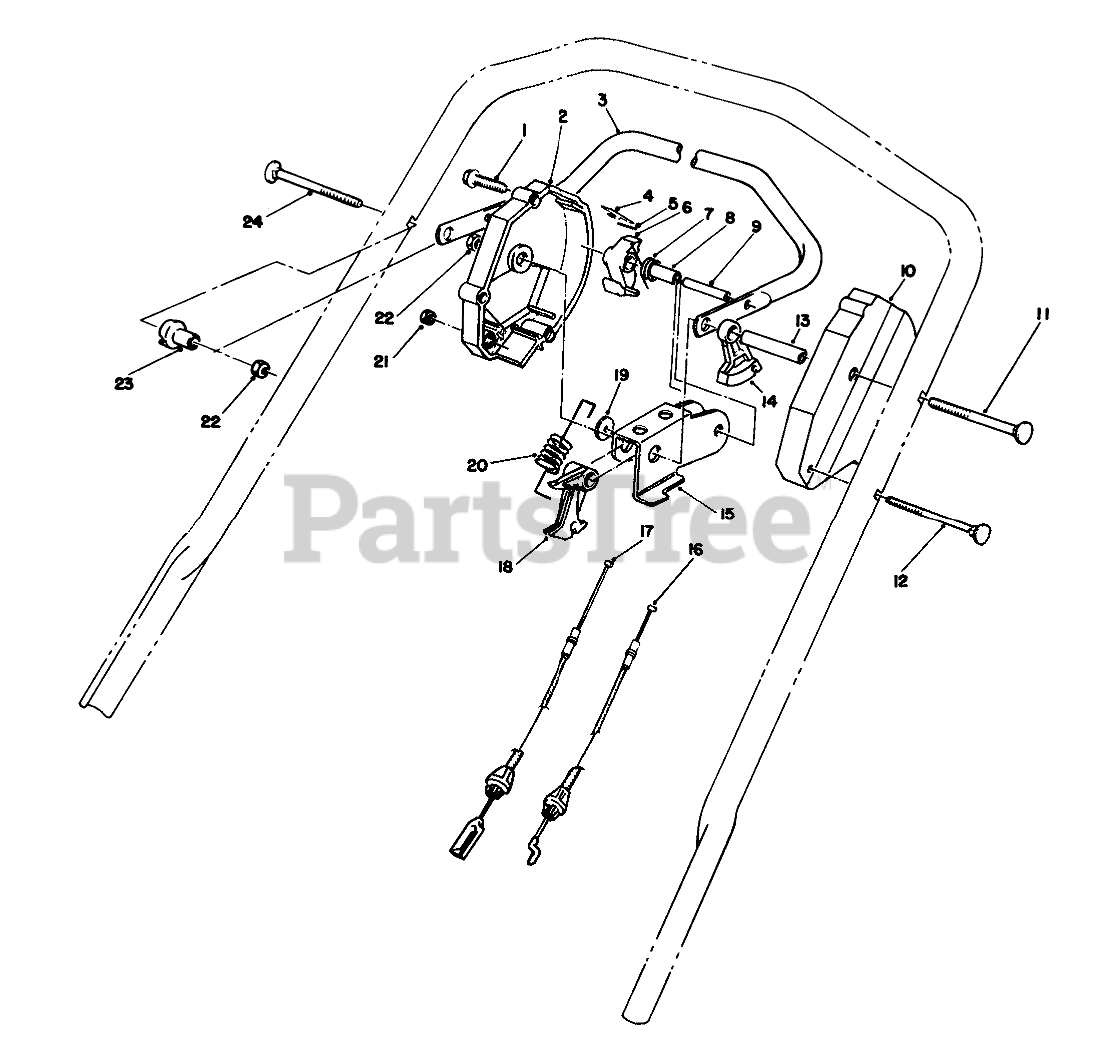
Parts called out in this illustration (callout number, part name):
1	SCREW-HWHTF
2	Housing-Control
3	Bar-Control
4	SPRING-LEAF
5	PIN-INSERT
6	HOOK-CONTROL
7	SPRING-TORSION
8	SPACER
9	PIN-ROLL, SLOTTED
10	HOUSING-CONTROL, LH
11	5/16-18 X 3 HNDLE SCREW
12	HANDLE SCREW
13	TUBING-SPACER
14	LEVER-TRACTION
15	ROCKER
16	Cable-Traction
17	Cable-Clutch
18	LEVER-CABLE
19	WASHER-NYLON
20	SPRING-DETENT
21	NUT-HEX
22	NUT-LOCK, NI
23	SPACER-SUPPORT
24	5/16-18 X 2 HNDLE SCREW
